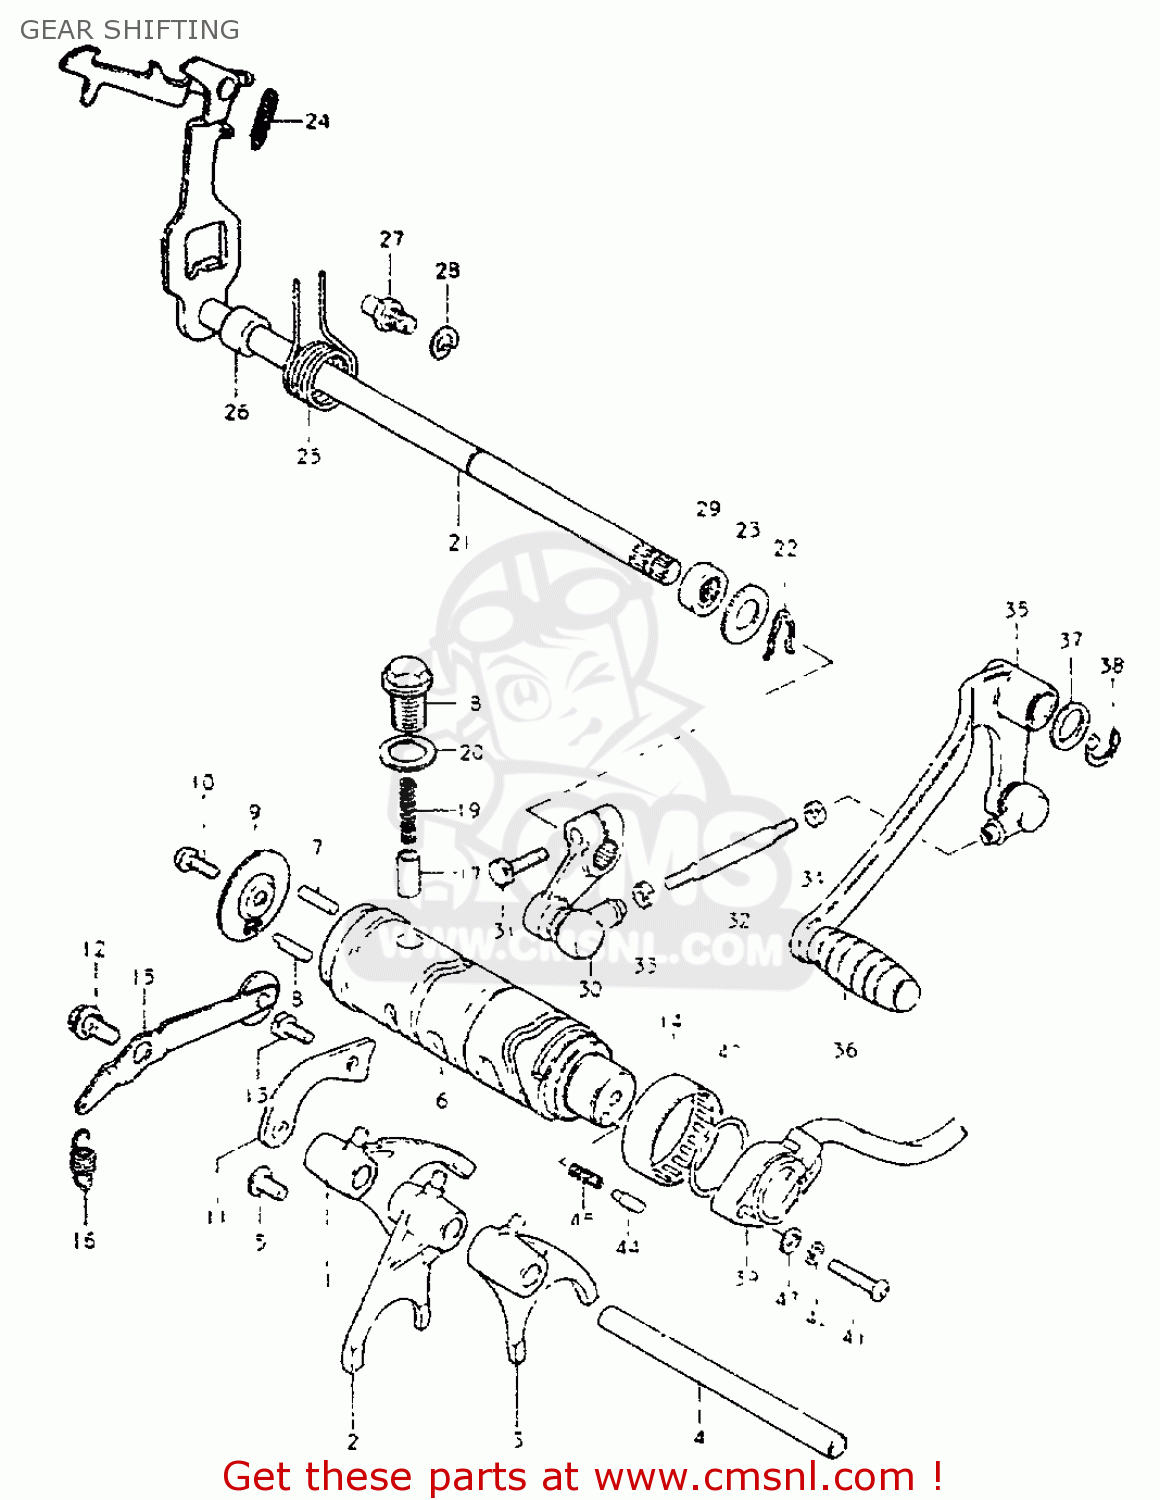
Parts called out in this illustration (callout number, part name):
1	FORK,GEAR SHIFT NO.1
2	FORK,GEAR SHIFT NO.2
3	FORK,GEAR SHIFT NO.2
4	SHAFT,GEAR SHIFT FORK
5	SCREW
6	CAM,GEAR SHIFT
7	PIN(4X18.5)
8	PIN
9	RETAINER,GEAR SHIFT CAM DR PIN
10	SCREW
11	GUIDE,GEAR SHIFTING CABLE
12	BOLT
13	BOLT
14	BEARING(40X47X12)
15	STOPPER,GEAR SHIFT CAM NO.1
16	SPRING
17	STOPPER,GEAR SHIFT CAM NO.2
18	HOLDER,GEAR SHIFT CAM STOP SPR
19	SPRING
20	GASKET(14X19.2X2) (NAS)
21	SHAFT,GEAR SHIFT
22	SPRING,RETAINER
23	WASHER (12.5X27X1.6)
24	SPRING
25	SPRING
26	SPACER(12X20X15.3)
27	STOPPER,GEAR SHIFT CAM
28	WASHER
29	OIL SEAL
30	ARM,GEAR SHIFT LINK
31	BOLT
32	ROD,GEAR SHIFT LINK
33	NUT
34	NUT
35	LEVER ASSEMBLY,GEAR SHIFTING
36	RUBBER,GEAR SHIFT PEDAL
37	WASHER(12.5X20X1)
38	CIRCLIP
39	TERMINAL BASE ASSY,GEAR SHIFT
40	O-RING (D:2.4 ID:26.2)
41	SCREW 5X20
42	LOCK WASHER
43	WASHER
44	PIN(5X15.5)
45	SPRING
